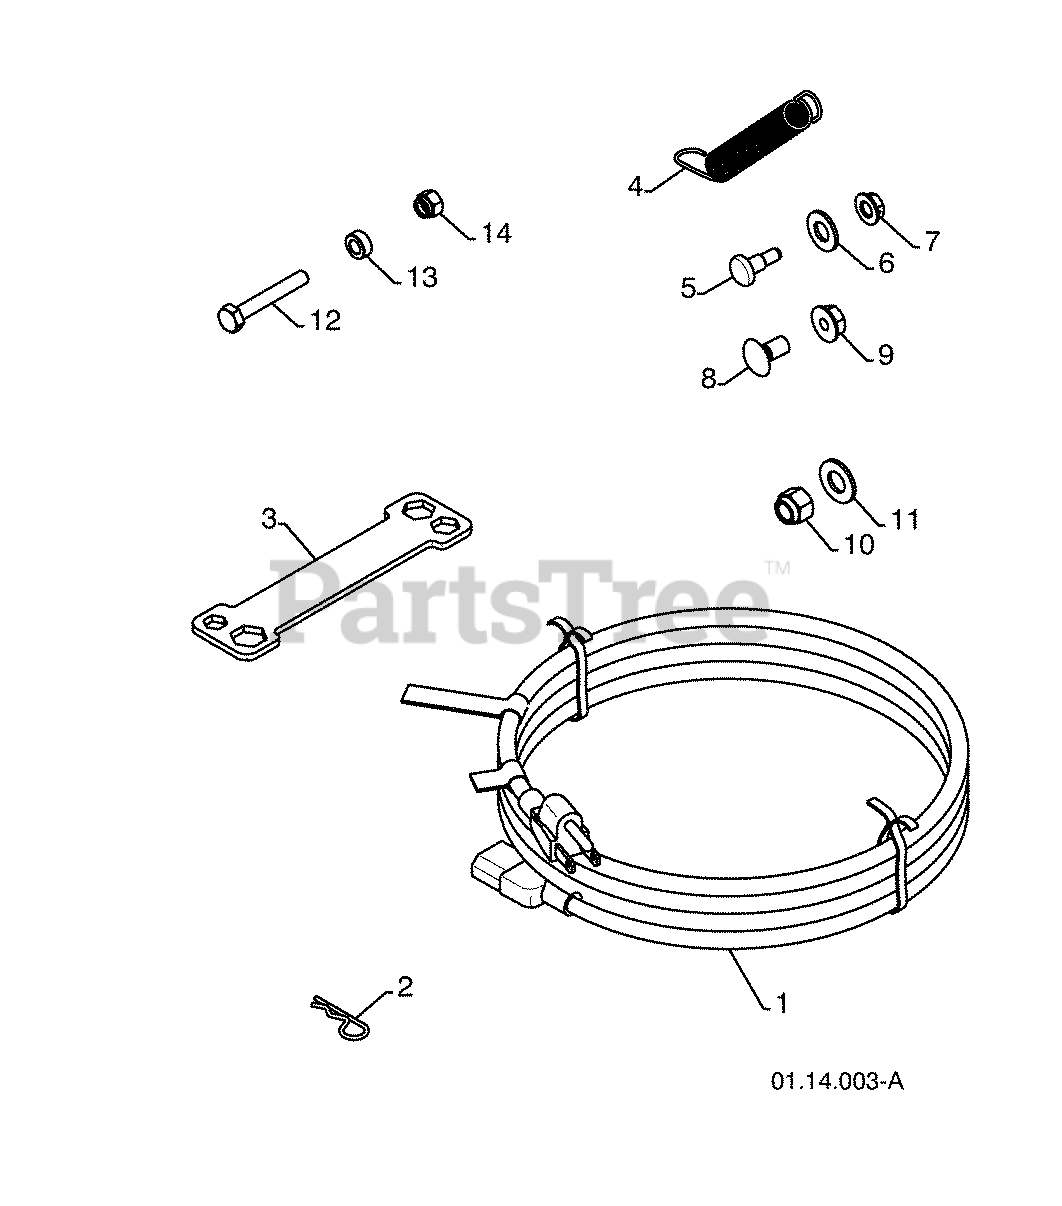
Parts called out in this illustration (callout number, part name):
1	POWER CORD
2	RETAINER PIN
3	WRENCH
4	REMOTE SPRING
5	SHOULDER BOLT 1/4-20
6	NYLON WASHER 1/4-20
7	LOCKNUT 1/4-20
8	CARRIAGE BOLT 5/16-18 X 5/8
9	LOCKNUT 5/16-18
10	LOCKNUT 3/8-16
11	WASHER 3/8
12	SHEAR BOLT 1/4-20 X 1-3/4
14	LOCKNUT 1/4-20
